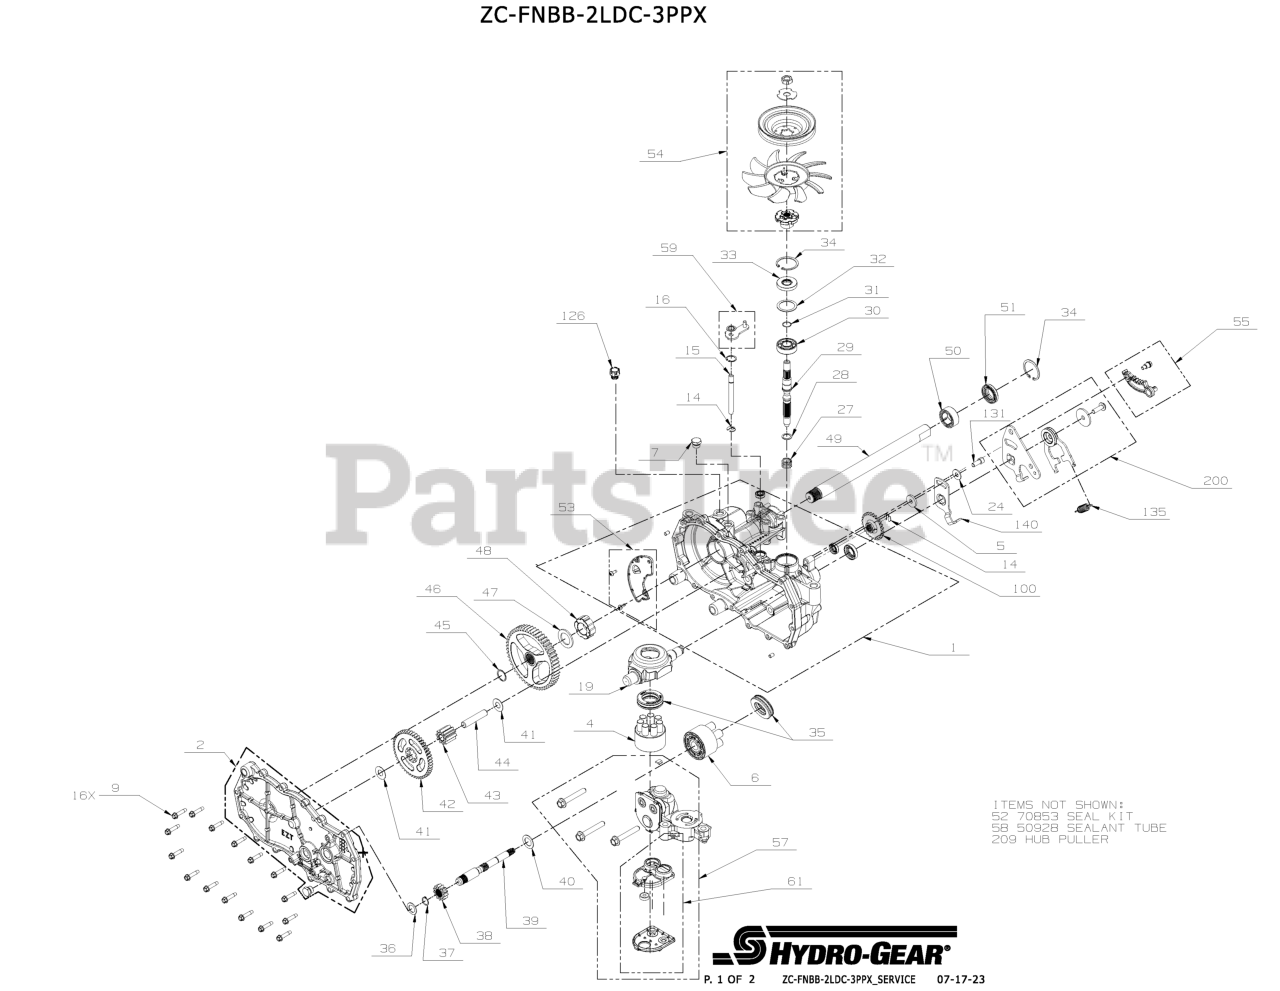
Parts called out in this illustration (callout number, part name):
1	KIT, HOUSING MAIN, LH
2	KIT, SIDE HOUSING, LH W/DRAIN
4	ASSY, BLOCK 7 PISTON
6	KIT, 10 CC BLOCK
7	PLUG EXT HEX VENT 9/16 18
9	SCREW,HEX WASHER 1/4-20X1.125
14	RING. RETAINING
15	ROD, BYPASS
16	RING, RET .750
19	TRUNNION, SWASHPLATE
27	SPRING. BLOCK
28	WASHER. THRUST .59 X .79 X .04
29	SHAFT, INPUT
30	BRG, BALL 17X40X12
31	RING, RET WIRE .561 ID
32	WASHER 1.23X1.56X.04
33	SEAL, LIP 17X40X7
34	RING, RET 1.56 INT
35	BEARING. THRUST 30 X 52 X 13
36	WASHER .63X1.0X.05
37	RING, RET 62 EXT
38	GEAR, 13T PINNION
39	SHAFT, MOTOR
40	WASHER .71 X 1.16 X .04
41	WASHER .5X1.0X.032
42	GEAR, 10T/48T
43	GEAR, 10T JACKSHAFT
44	PIN, JACKSHAFT
47	WASHER, 1.018 X 1.571 X .105 FLAT
48	BUSHING, SLEEVE (INBOARD)
49	SHAFT, AXLE 1.00 X 13.02, DD
52	KIT, SEALS AND RETAINING
53	KIT, EXPANSION PLATE LH
54	FAN PULLEY KIT 4.5X1.625
55	BRAKE ARM-RH, EZT
57	KIT, CENTER SECTION, W/FILTER - LH
58	SEALANT TUBE 10.1OZ.
59	KIT, BYPASS ARM
61	KIT, FILTER
100	DISC, COG BRAKE
126	ASSEMBLY, FITTING 9/16-18 BREATHER
131	KIT, RTN SCREWS
135	SPRING, EXTENSION
140	ARM, NEUTRAL LEFT
200	RING, RTNG .
209	HUB PULLER 5 BLT
